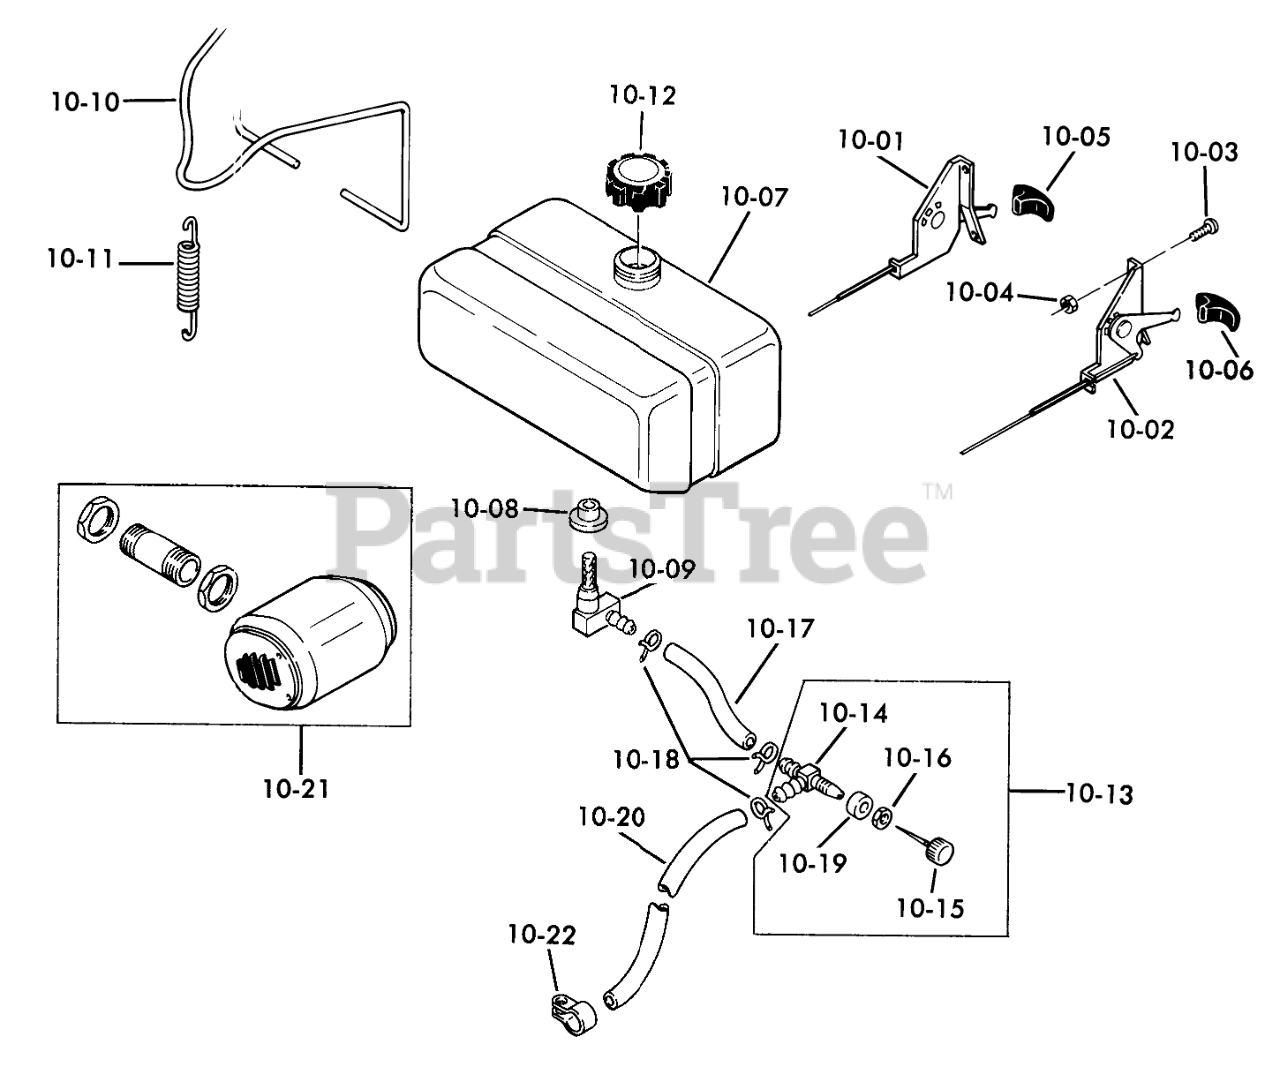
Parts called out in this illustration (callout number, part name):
10-01	Throttle Control
10-02	Ass-y. Control-Choke
10-03	SCREW
10-04	#10-24 Kep-Nut
10-05	KNOB-THROTTLE
10-06	KNOB-CHOKE
10-07	ASSY-FUEL TANK
10-08	BUSHING
10-09	FITTING FUEL TANK
10-10	Hold Down Wire
10-11	CLUTCH SPRING
10-12	Cap
10-13	S/A FUEL VALVE
10-14	VALVE BODY
10-17	Fuel Hose 4.5"
10-18	Clamp
10-19	SPACER
10-20	Fuel Hose 18"
10-21	Assy-Exhaust
10-22	CLAMP-HOSE
